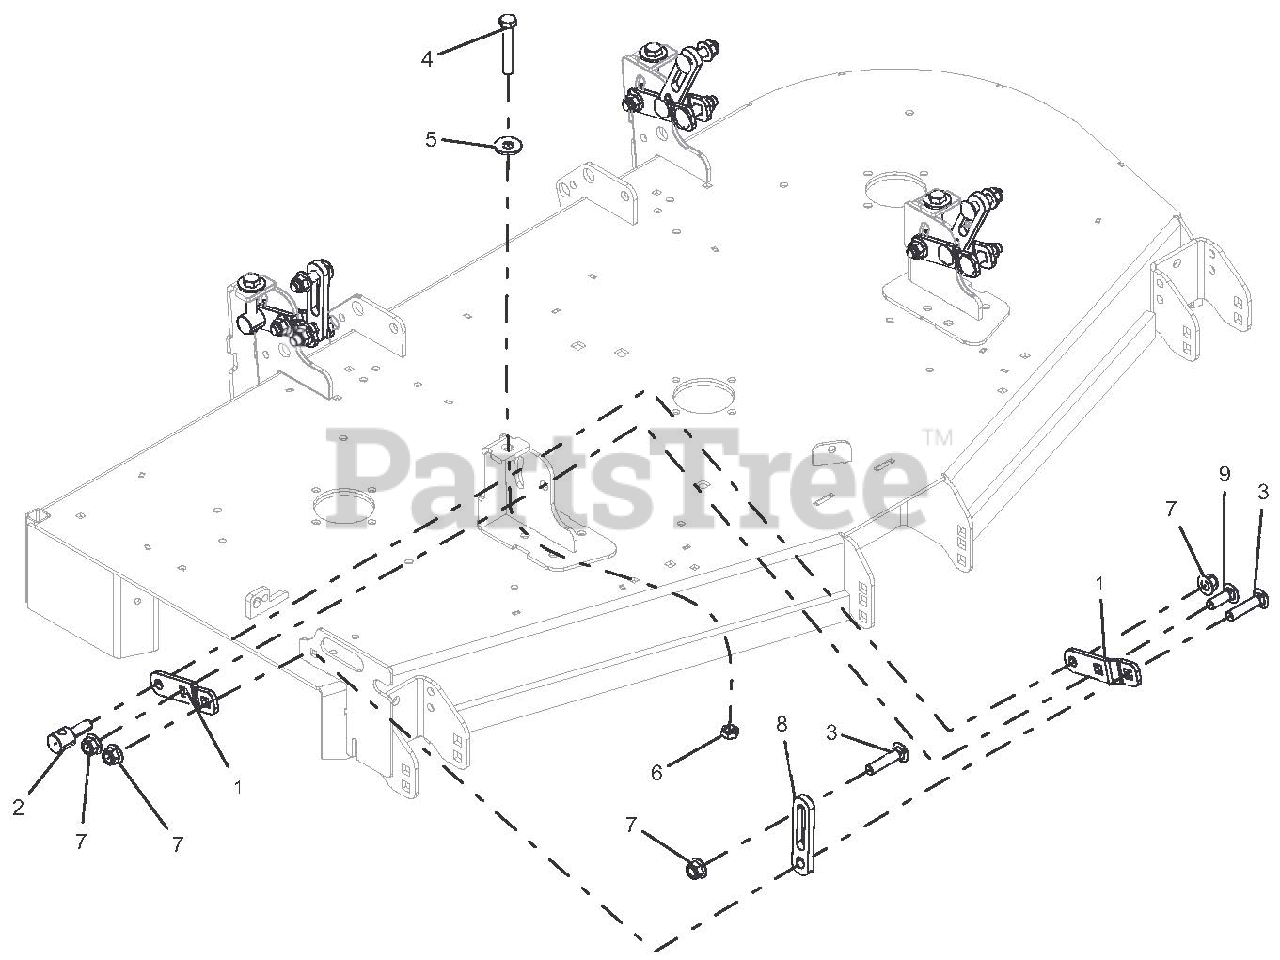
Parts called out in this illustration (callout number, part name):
1	BRKT, DECK LEVELING-BLACK
2	TRUNNION, .50-13
3	BLT-RDHDSQNK .50-13X2.25 G5 Y
4	BLT-HEX .50-13X3.00 GR5 FTH YWZC
5	WSHR-FL-STL.563X1.38X.109YWZC
6	NUT, JAM .500-13 YWZC
7	NUT-LK-NYL-FLG .50-13 YWZC
8	LINK, DECK LIFT - SHORT
9	BLT-RDHDSQNK .50-13X1.50 G5 YWZC
